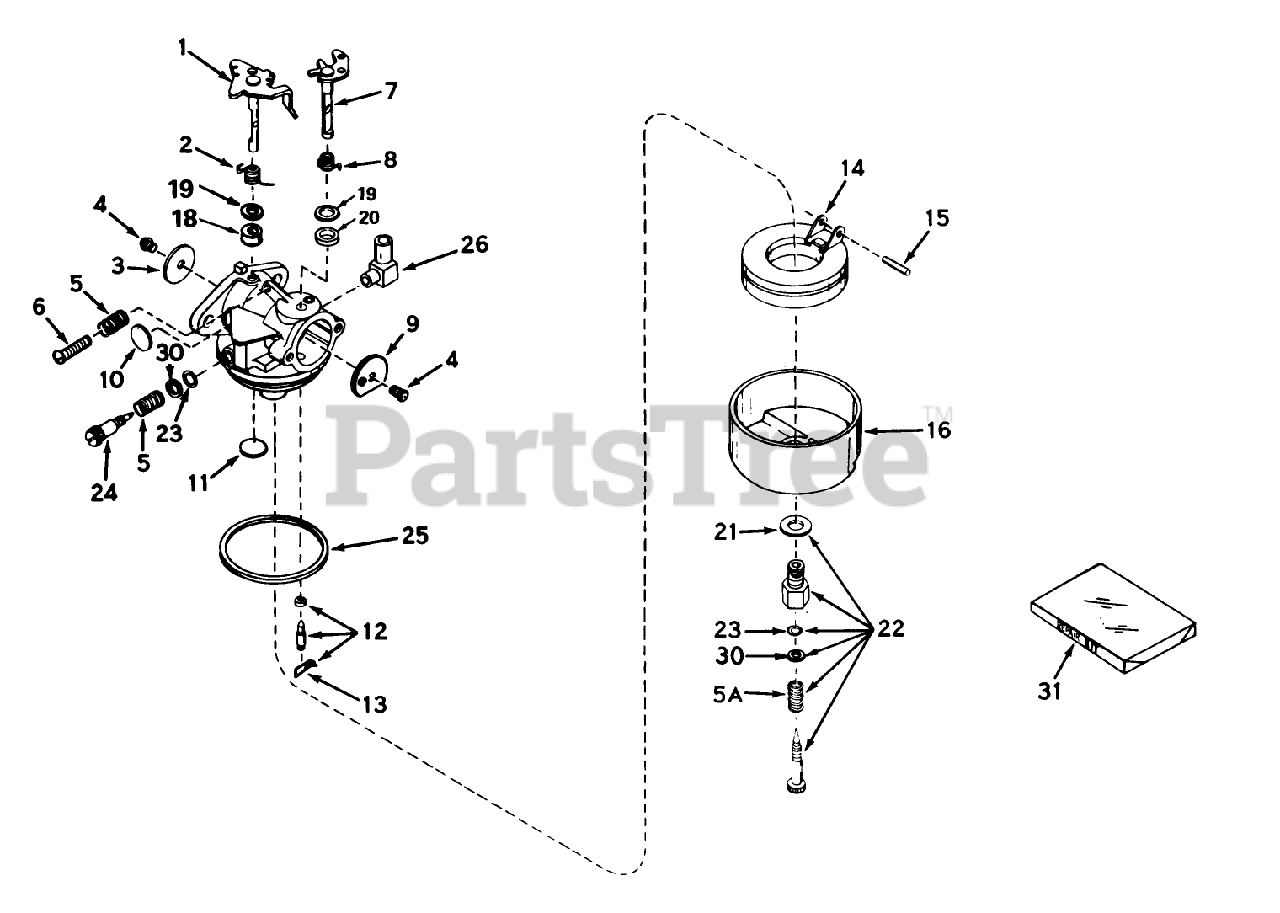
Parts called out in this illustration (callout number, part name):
1	Shaft/Lever-Throttle
2	Spring-Return, Throttle
3	Shutter-Throttle
4	Screw-Shutter
5	Spring-Tension
5A	Spring
6	Screw-Throttle Crack Screw / Idle Speed
7	Shaft Lever Assy., Choke
8	Spring-Choke
9	Shutter-Choke
10	Plug-Welch, Idle Mixture Well
11	Plug-Welch, Atmospheric Vent
12	Inlet Needle, Seat Clip Assy. (Incl. No. 13)
13	Clip-Spring
14	Float
15	Shaft-Float
16	Bowl-Float (no drain)
18	Seal-Dust
19	Washer-Seal, Dust
20	Seal-Dust
21	Washer-Bowl Nut
22	Adjustment Screw Assy., Main (Incl. Ref. #5A, 21, 23 30)
23	ORing
24	Screw, Idle Adj.
25	O Ring-Bowl, Float
26	Fitting-Fuel Inlet
30	Washer
31	Repair Kit
